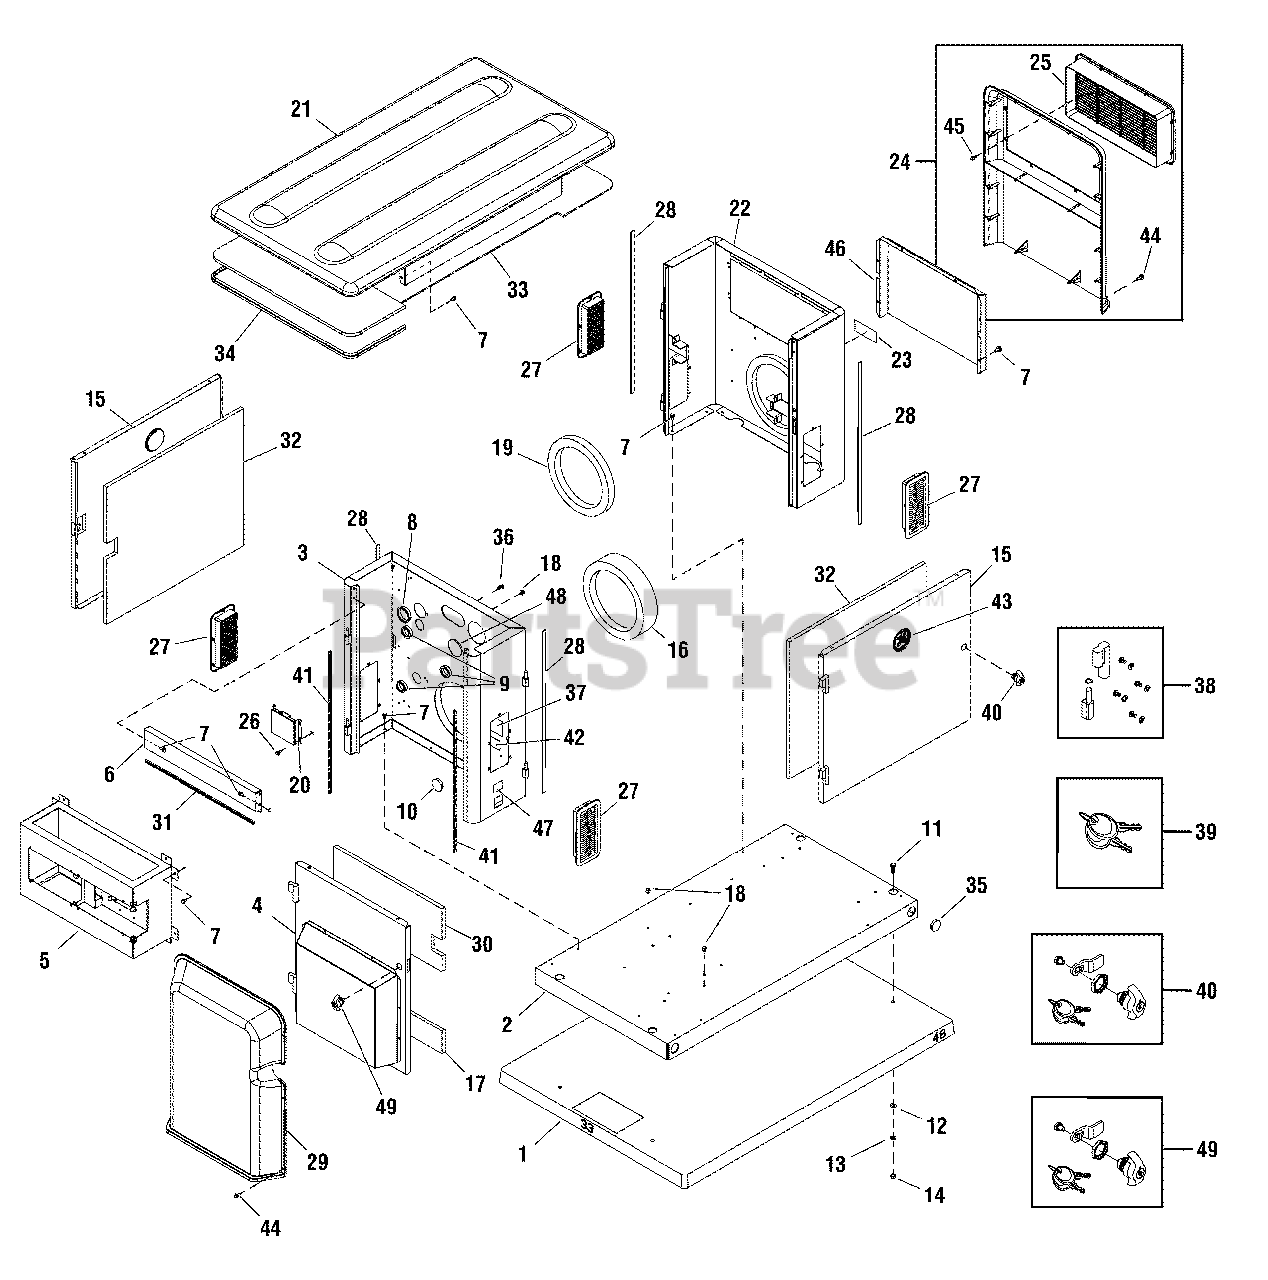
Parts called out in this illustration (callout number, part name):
3	BULKHEAD, Engine, Complete
7	BOLT
11	* CAPSCREW, Hex Head, 3/8-16 x 1
12	* WASHER, Flat, 3/8 - M10
13	* WASHER, Lock, 3/8
14	* NUT, 3/8-16
16	SEAL, Foam
19	SEAL, Foam
20	REGULATOR, Voltage
22	BULKHEAD, Alternator
42	DECAL
47	DECAL
